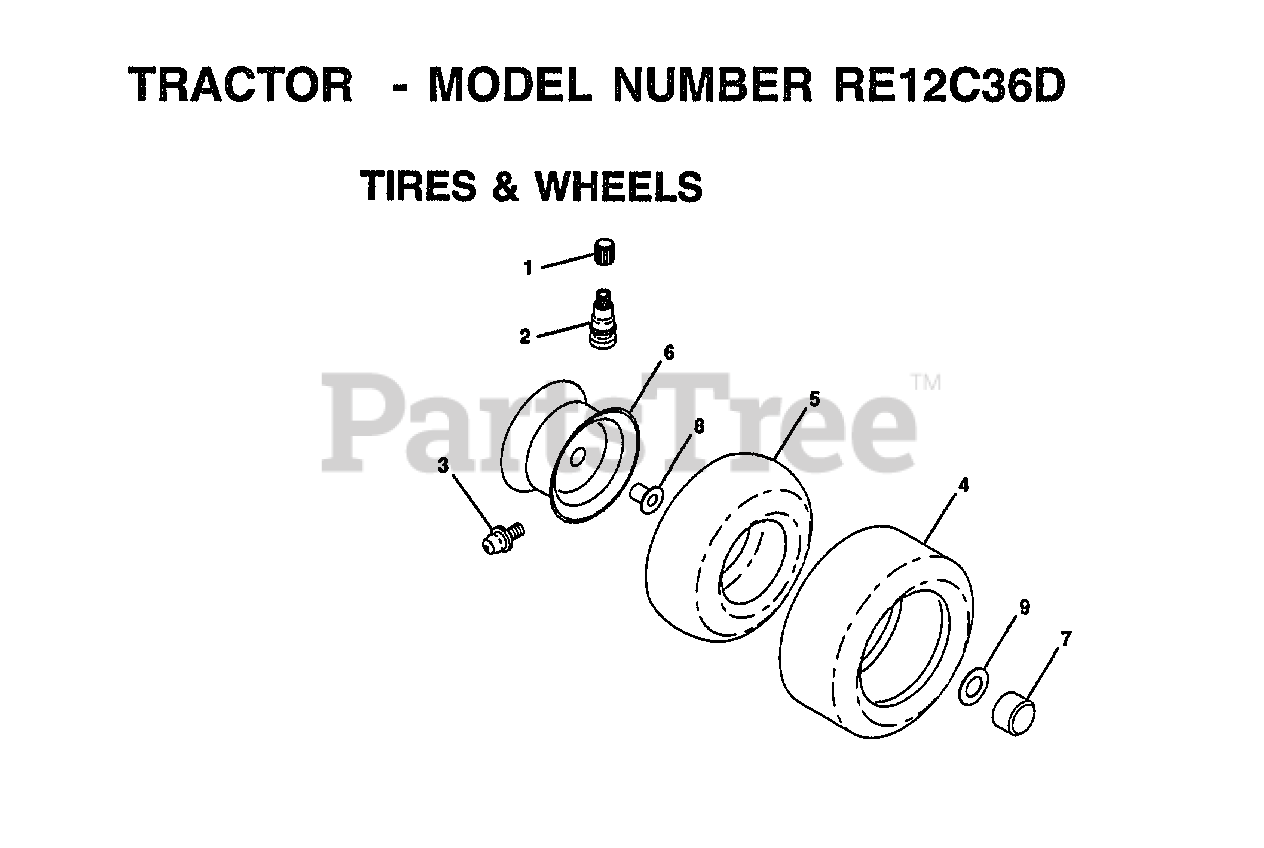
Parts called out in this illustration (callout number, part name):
1	VALVE CAP
2	VALVE STEM LT
3	FITTING LT
5	TUBE.5.3/4.5/6
5	TUBE.16X6.5/7.5-8
6	"RIM FRONT 6"""
6	"RIM ASM REAR 8"""
7	HUB CAP
8	"FLANGE, BEARING"
9	WASHER
